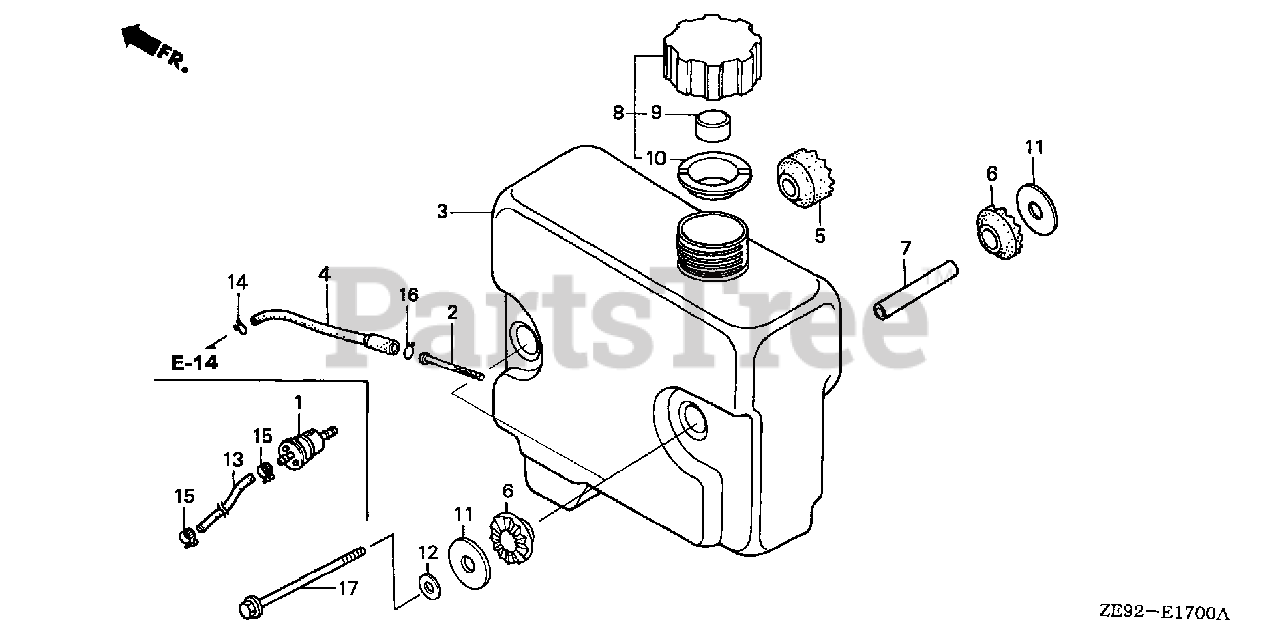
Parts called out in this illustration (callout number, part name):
2	FILTER, FUEL
3	TANK, FUEL
4	TUBE, FUEL
5	RUBBER B, TANK MOUNTING
6	RUBBER B, TANK MOUNTING
7	COLLAR, TANK SETTING
8	CAP ASSY., FUEL TANK
9	SPONGE, FUEL CAP BREATHER
10	GASKET, FUEL CAP
11	WASHER, TANK MOUNTING
12	WASHER, PLAIN (8MM)
14	CLIP, TUBE (B8)
16	CLIP, TUBE (C11)
17	BOLT, FLANGE (8X95)
